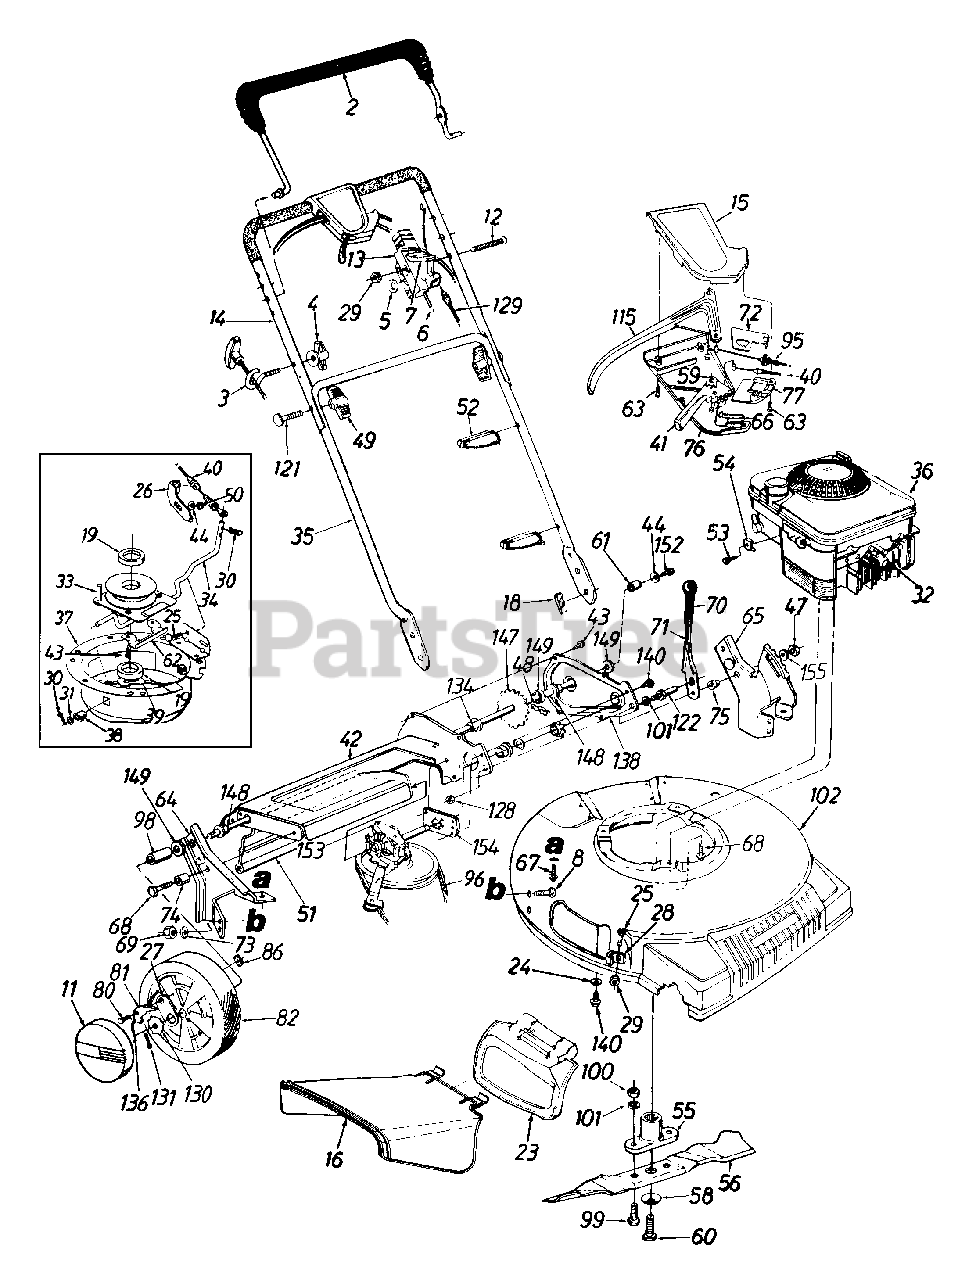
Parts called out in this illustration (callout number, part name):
2	Control Handle
3	Rope Guide
4	Handle Knob 1/4-20 Thd.
5	Curved Spring Wash..66" I.D.
6	Throttle Wire - 55" Lg.
7	Throttle Lever
8	Carriage Bolt 5/16-18 x .62" Lg.
11	Hub Cap
12	Oval C-Sunk Mach. Scr.
13	Throttle Body
15	Upper Control Housing
16	Side Chute Deflector
18	Internal Cotter Pin 5/16" Dia.
19	Spacer .88" I.D.
23	Mulch Plug Ass'y.
24	Bell-Wash. .265" I.D. x .75" O.D.
25	Carriage Bolt 1/4-20 x .5" Lg.
30	Cotter Pin 3/32" Dia. x .75"
31	FI-Wash. .328" I.D. x .68"
32	Spark Plug Insulator
33	Pulley Ass'y.
34	Shift Rod
36	Engine
37	Housing Ass'y.
38	Flanged Bushing
39	Wave Washer .88" I.D.
40	6 Spd. Cable
41	6 Spd. Shift Lever
44	Bell-Wash. 1/4" I.D.
47	Hex Patch L-Nut 3/8-24 Thd.
48	#48 Chain .500" Pitch x 38 Links
49	Hand Knob
50	Hex L-Nut 1/4-20 Thd.
51	Rear Flap 4.8" x 17.5" Lg.
52	Cable Tie
53	Hex Wash. Hd. Scr. #10-32 x .62" Lg.
54	Casing Clamp
55	Blade Adapter
56	21" Mulching Blade
58	Bell-Wash..39" I.D. x 1.14" Q.D.
59	Gear Insert
60	Hex Bolt 3/8-24 x 2.5" Lg. (Gr. 8)
61	Spacer .513" I.D.
67	Hex B-Tap Scr. 5/16-18
68	Hex TT-Tap Scr. 3/8-16
69	Hex Nut 5/16-18 Thd.
71	Height Adj. Lever
72	6 Spd. Rack Cable Brkt.
73	Bell-Wash. 5/16" I.D.
74	Spacer .383" I.D.
75	Shld. Spacer .5" Dia.
76	Lower Control Housing
77	Cable Mounting Cap
80	Shld. Scr. .342" Dia. x .268
81	Pawl - R.H.
82	Wheel Ass'y Comp. (Beige Rim)
86	Weld Top L-Nut 1/4-20 Thd.
95	S.P. Cable
96	"V"-Belt
98	Sleeve .526" I.D.
99	Hex Bolt 3/8-24 x 1.0" Lg.
100	Hex Nut 3/8-24 Thd.
101	L-Wash. 3/8" I.D.
121	Curved Hd. Bolt 5/16-18 x 2" Lg.
122	Shld. Pin 1.43" Lg.
128	Hex Jam Nut 3/8-24 Thd.
129	Control Cable - 39"
130	Ratchet Wheel 1.62" O.D.
131	Cotter Pin 1/8" Dia. x 1"
134	Hex Flange Bearing
136	Spring - Nylon
147	Rear Shaft Ass'y. 21 44" Lg.
148	Hex Flange Brg .506" I.D.
149	Fl-Wash. 531" I.D. x .930"
152	Hex Bolt 1/4-20 x .62" Lg. (Gr. 5)
153	Transmission Comp.
155	Fl-Wash. 385" I.D. x .87" O.D.
